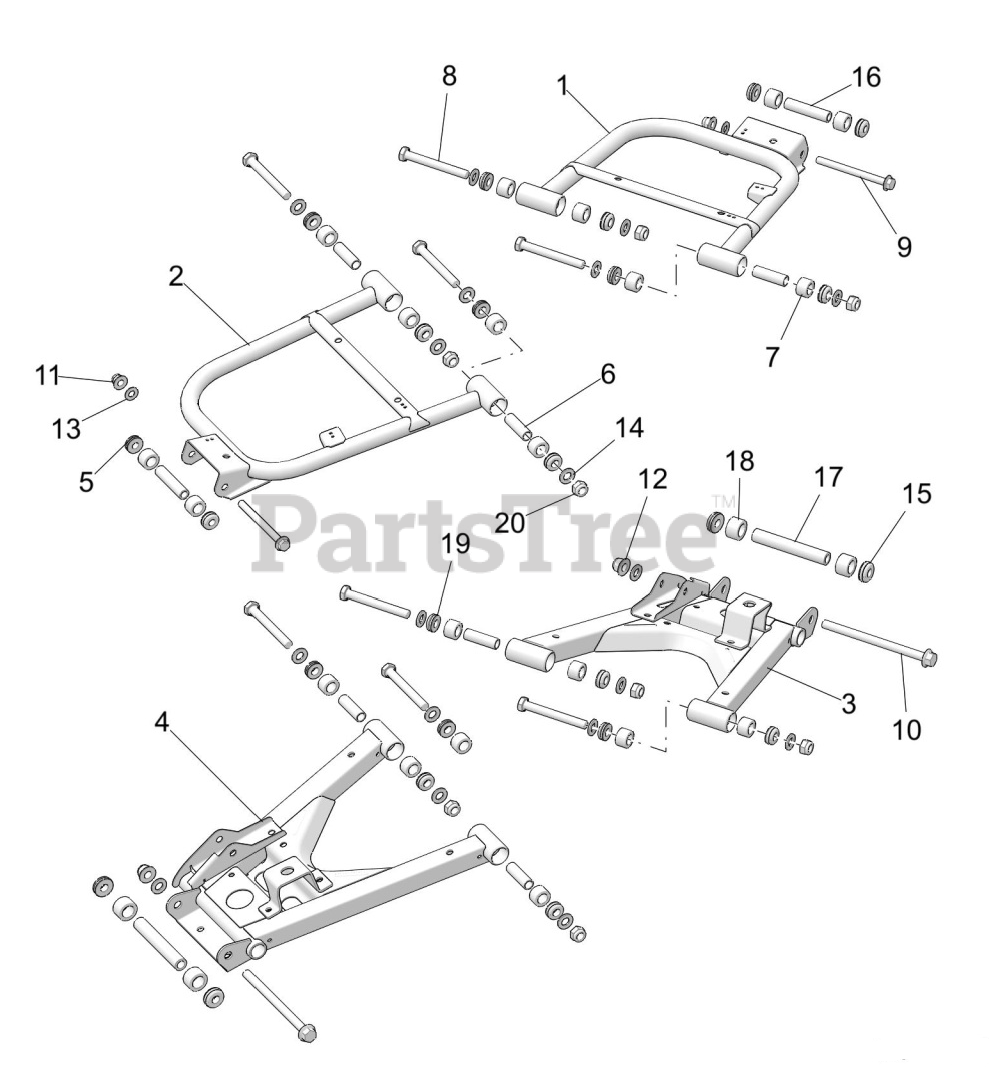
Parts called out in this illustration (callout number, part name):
1	WELD-CONTROL ARM-RR-UPR-LH-BLK
2	WELD-CONTROL ARM-RR-UPR-RH-BLK
3	WELD-CONTROL ARM-RR-LWR-LH-BLK
4	WELD-CONTROL ARM-RR-LWR-RH-BLK
5	ASM-PIVOT CAP- SEALED- M10
7	BUSHING-STANDARD-SUSP-M10
8	SCR-HH-M12X1.75X100 10.9 ZPC
9	SCR-HXFL-M10X1.25X115 10.9 SPC
10	SCR-HXFL-M12X1.5X170 10.9 ZOD
11	NUT-M10X1.25-FLG-NYLOC-OLIVE D
12	NUT-M12X1.5-FLG-NYLOC-OLIVE D
13	WASHER-3/8 FW
14	WSHR-13.0X24.0X2.5 ZPC
15	ASM-PIVOT CAP-SEALED M12
16	SHAFT-PIVOT-SHORT-M10
17	SHAFT-PIVOT-LONG-M12
18	BUSHING-STANDARD-SUSP-M12
19	ASM-PIVOT CAP-SEALED-M12
20	NUT-NYLOK-M12X1.5-0600110
